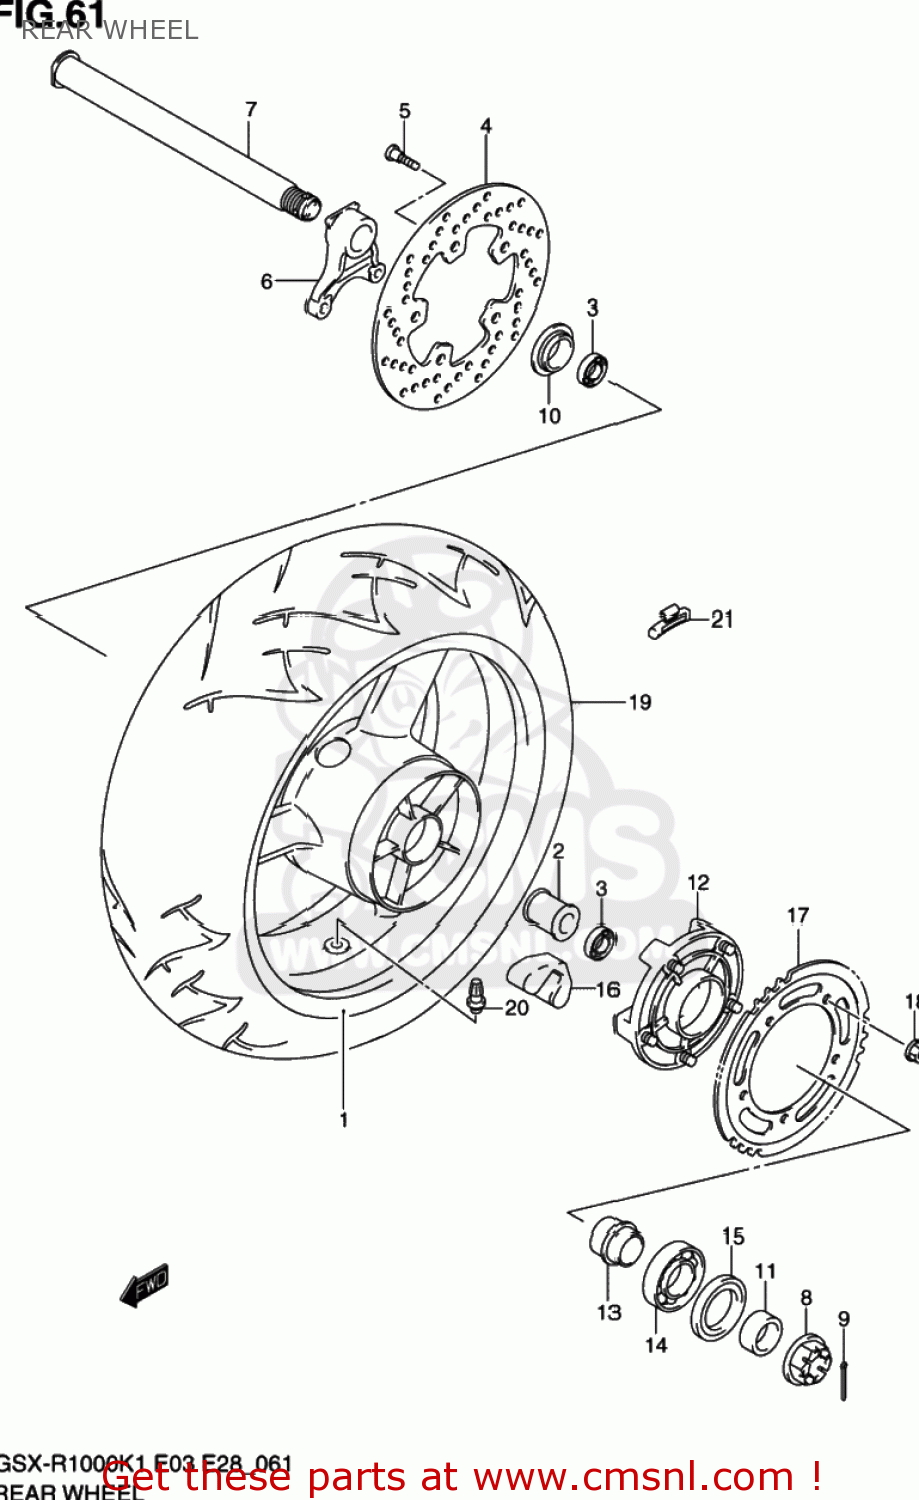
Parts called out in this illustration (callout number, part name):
1	WHEEL,REAR,17X
2	SPACER,RR HUB BEARING
3	BEARING(28X52X12)
4	DISC,REAR BRAK
5	BOLT(8X33)
6	BRACKET,REAR C
7	AXLE,RR
8	NUT
9	PIN, COTTER
10	SPACER,RR AXLE,R
11	SPACER,RR AXLE,L
12	DRUM, REAR SPROCKET
13	RETAINER,RR SPROCKET DRUM
14	BEARING
15	SEAL,OIL(39X65X7)
16	ABSORBER,RR HUB SHOCK
17	SPROCKET,RR(42T-530)
18	NUT
19	TIRE, REAR, 190/50ZR17 (73W)
20	VALVE ASSY,WHEEL RIM(TR412)
21	WEIGHT,BAL. 30
